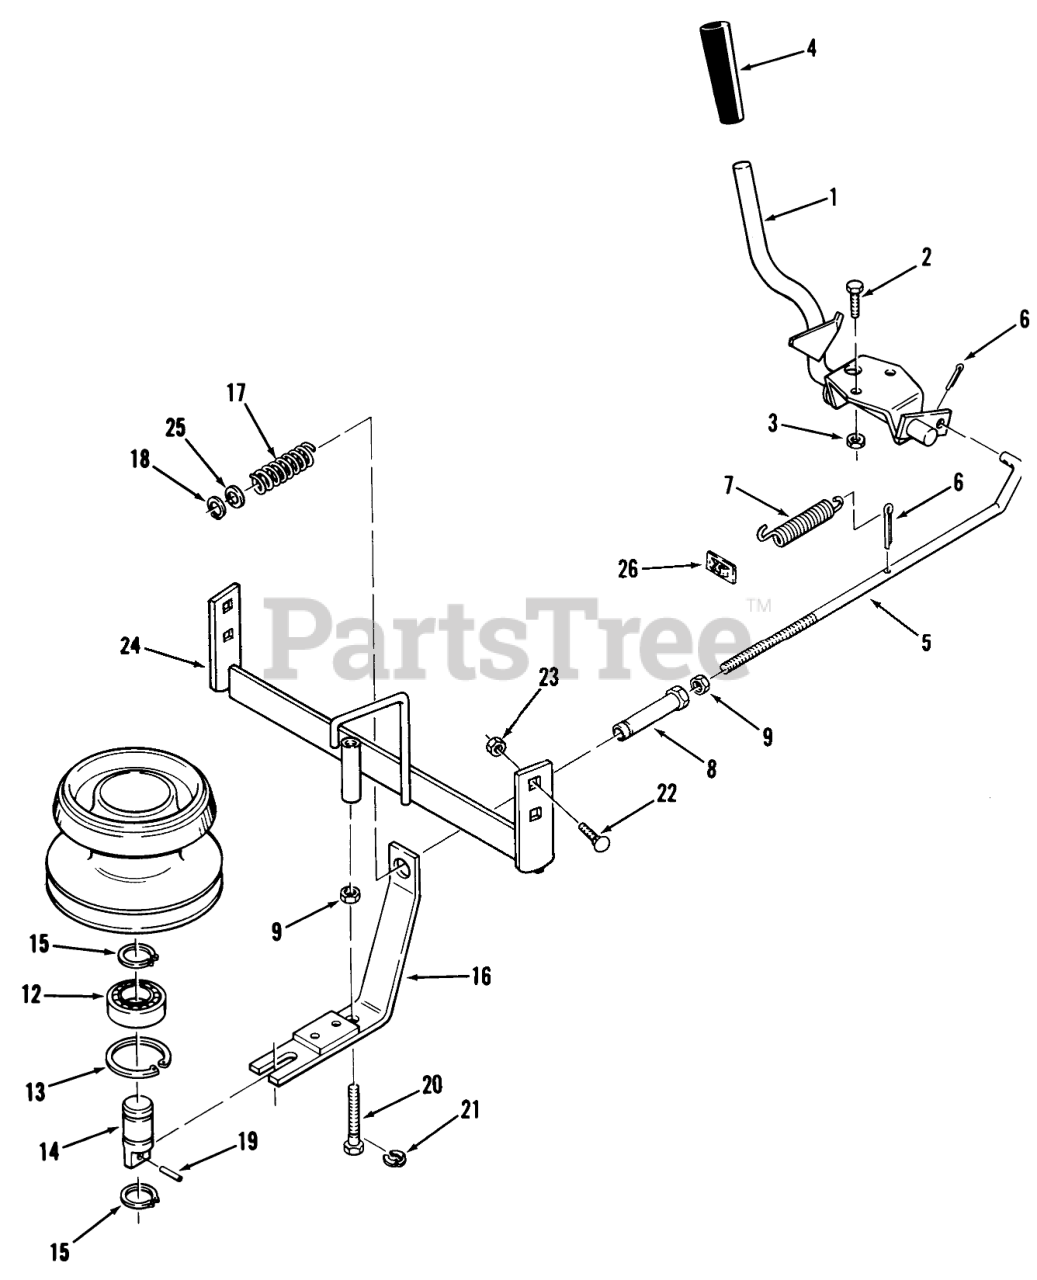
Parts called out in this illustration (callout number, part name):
1	ASSY-HANDLE
2	Bolt
3	Nut
4	GRIP
5	PTO Clutch Rod
6	Cotter Pin
7	Spring
8	TUBE-CLUTCH SPACER
9	Jam Nut 5/16-18
12	BaIl Bearing
13	Ring-Snap
14	Shaft Clutch Hsg
15	RING-SNAP, EXTERNAL
16	ASM-CLUTCH BRAKE PTO
17	SPRING-CLUTCH
17	SPRING-COMPRESSION
18	Retaining Ring
19	SPIROL PIN 7/32X7/8
20	SCREW-CLUTCH ADJUST
21	E-Ring
22	Bolt
23	Nut
24	Clutch Mounting Bracket 216-5 Only
24	Clutch Mounting Bracket
25	Washer
26	SPEED NUT
